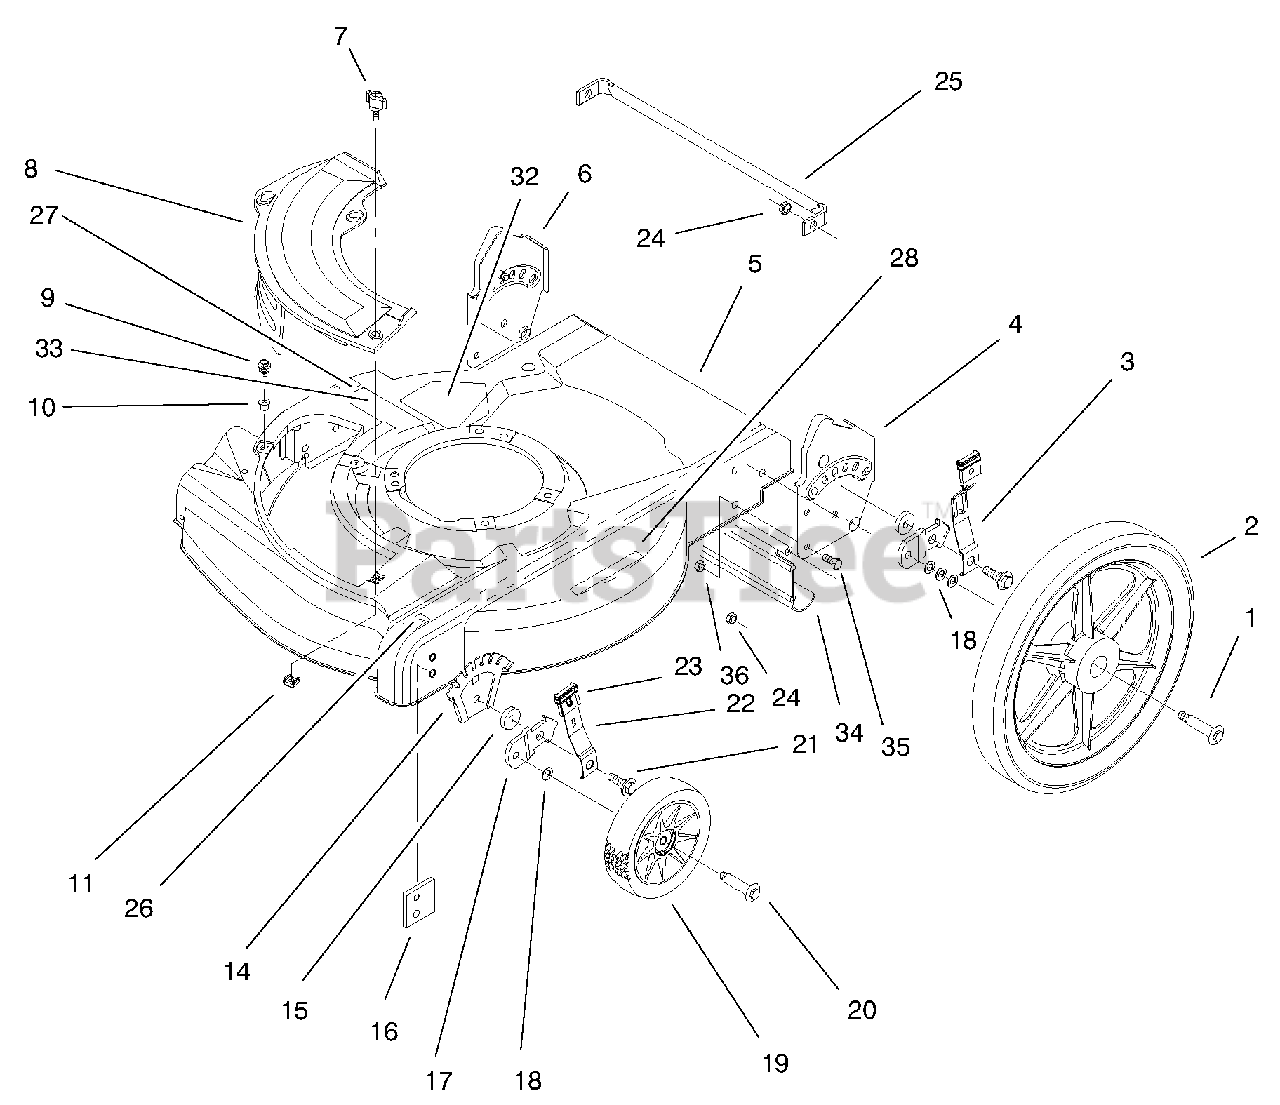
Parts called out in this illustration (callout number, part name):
1	Shoulder Bolt
2	Wheel-14 Inch
3	Assy-Spring Arm
4	Assy-Bracket Handle,LH
5	Asm Housing/Baffle HP
6	Assy-Bracket Handle,RH
8	Plate-Mulch
9	Screw-Sems
10	Grommet-Plastic
11	Nut-Cage
14	Plate-Hght Adj
15	Washer-Wheel
16	Plate-Baffle
17	Brkt-Whl Ht Adj
18	Washer-Wheel Bolt
19	6" Wheel & Tire ASM
20	Bolt-Shoulder 6" Wheel
21	Bolt-Shoulder
22	Arm-Front Spring
23	Knob-Height Adj Lever
24	Nut-Lock Ni
25	Brace-Handle Bracket
26	Decal-HOC L
27	Decal-HOC R
28	Decal-Safety Instruct
32	Decal-Danger
33	Decal-Warning
34	Shield-Trailing
35	Screw-Hex Hd
36	Nut-Lock
